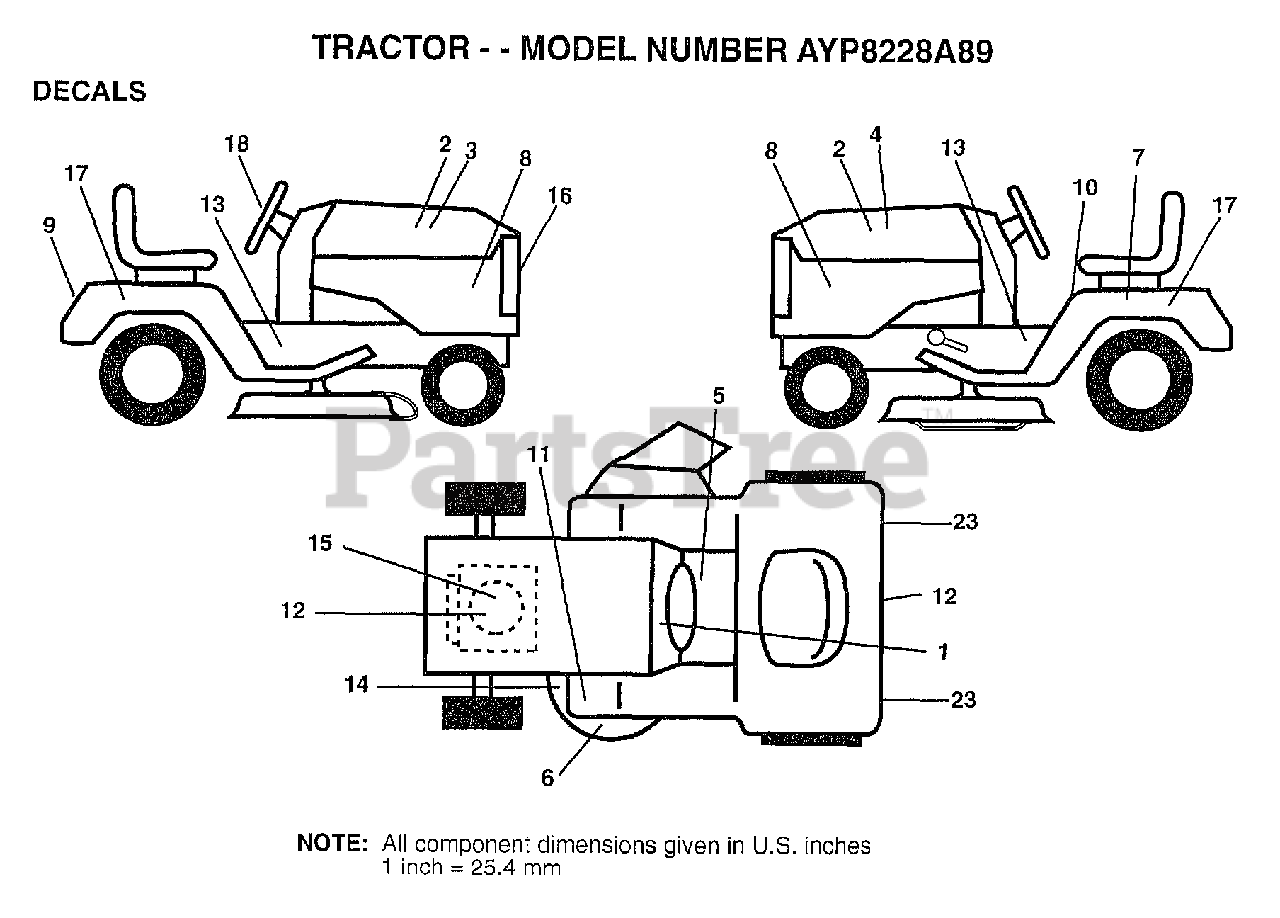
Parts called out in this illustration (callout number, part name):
1	"DECAL-INST,OPER"
2	NAMEPLATE.HD.WIZA
3	DECAL.HD.RH.WIZRD
4	DECAL.HD.LH.WIZRD
5	DECAL BRAK PARK
6	DECAL DECK WIZ +
7	DECAL.BATRY.3-3908
8	DECAL.SIDE.PANEL
10	"DECAL DANGER,FEND"
12	DECAL D-BAR CNTRL
13	DECAL CHASSIS 50
15	DECAL, ENGINE
16	DECAL.GRILLE.WIZ+
17	DECAL.FENDER.WIZ
18	DECAL INS STG WHL
23	REFLECTOR-TAIL YT
